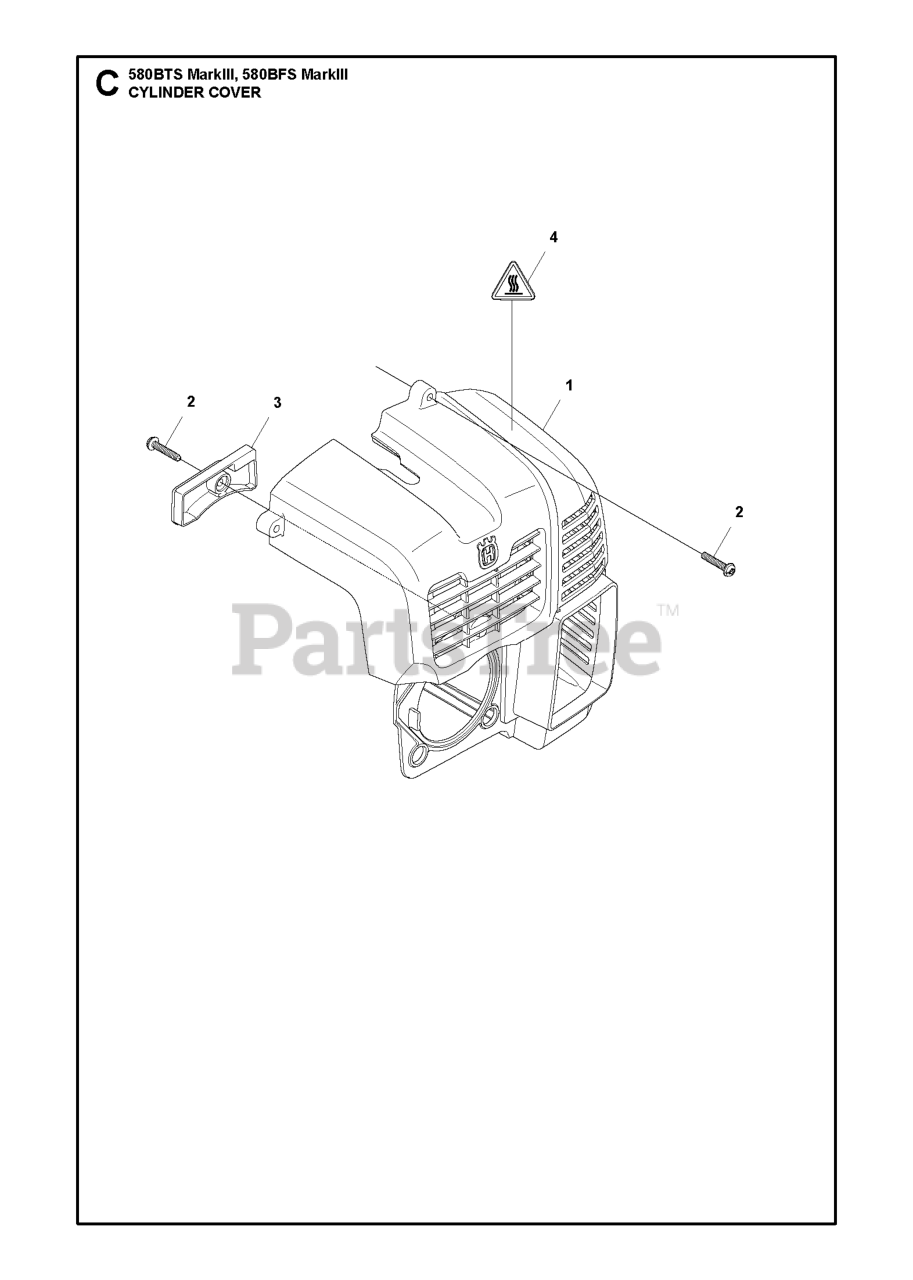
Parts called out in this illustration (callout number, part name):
1	COVER ENGINE
3	COIL COVER
4	LABEL HOT CAUTION
